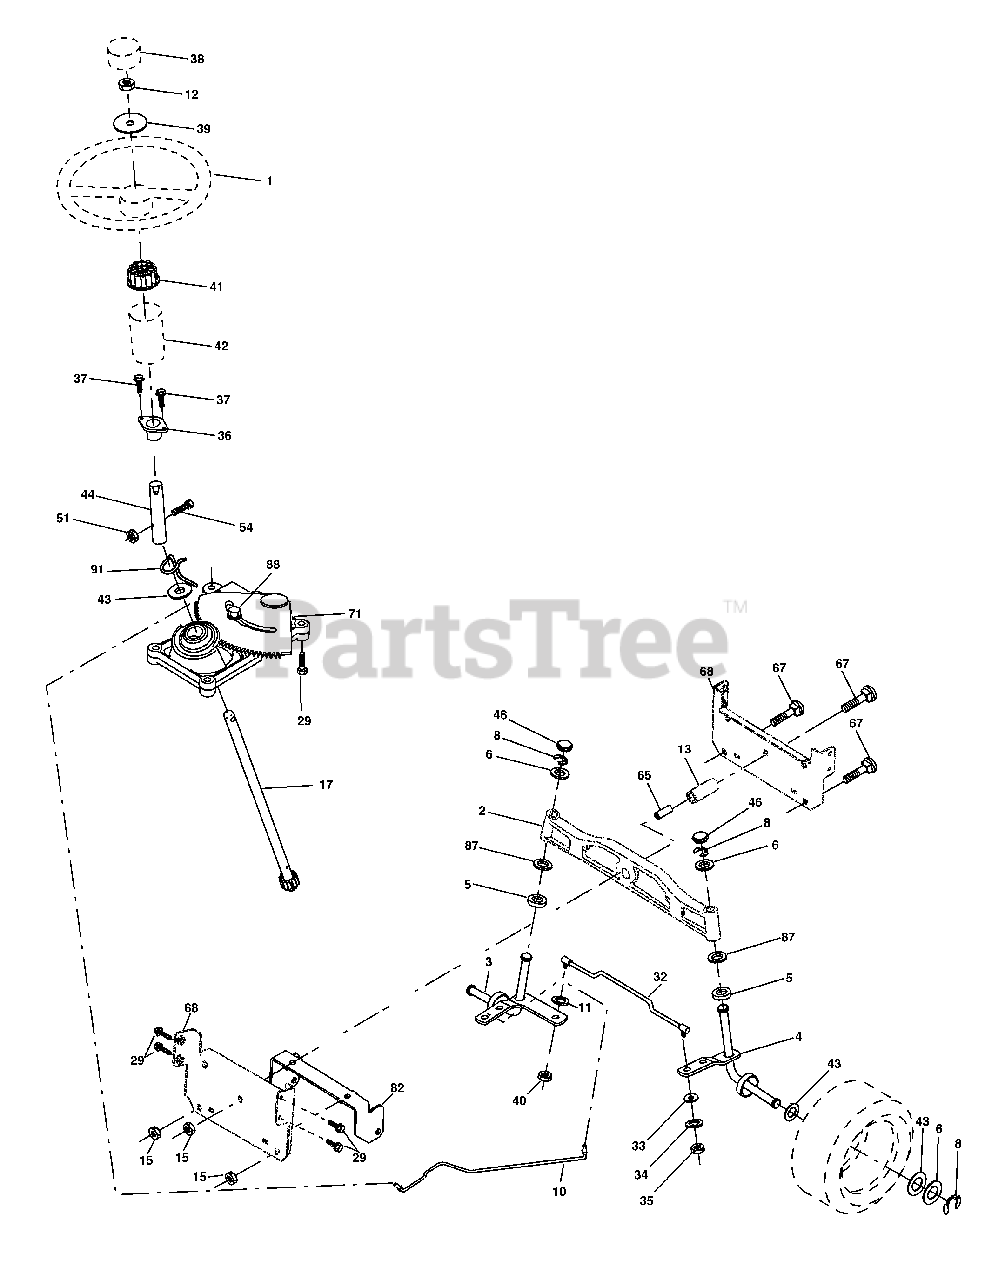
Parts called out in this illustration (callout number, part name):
1	Wheel Steering
2	Axle Asm
3	Spindle Asm LH
4	Spindle Asm RH
5	Bearing Race Thrust Harden
6	Washer 25/32 X 1-5/8 X 16 Ga
8	Ring Klip #t5304-75
10	Link Drag
11	Washer Lock Hvy Hlcl Spr 3/8
12	Nut Hex Jam Toplock 1/2-20 UNF
13	Spacer Brg Axle Front
15	Nut Hex Flange Lock
17	Shaft Asm Steering
29	Screw 3/8-16 x .75
32	Rod Tie
33	Washer 11/32 x 3/4 x 16 Ga
34	Washer Lock Hvy Hlcl Spr 5/16
35	Crownlock Nut 5/16-24 Unf
36	Bushing Strg
37	Screw
38	Insert Cap Strg Wh
39	Washer 9/16 X 1 1/20 X 11 Ga
40	Lock nut
41	Adaptor Wheel Strg
42	Boot Steering Dash
43	Washer 25/32 X 1 1/4 X 16 Ga
44	Extension Steering Shaft
46	Cap Spindle Fr Top Blk
51	Nut Crownlock 1/4-28
54	Bolt Hex 1/4-28 UNF x 1-1/4 Gr. 8
65	Spacer Brace Axle
67	Bolt Rdhd Sq 3/8-16 Unc x 2-3/4
68	Axle, Brace
71	Steering Asm
82	Bracket Susp Chassis Front
87	Washer Flat .781 x 1-1/2 x .14
88	Bolt Shoulder 7/16-20 Unc
91	Clip Steering
